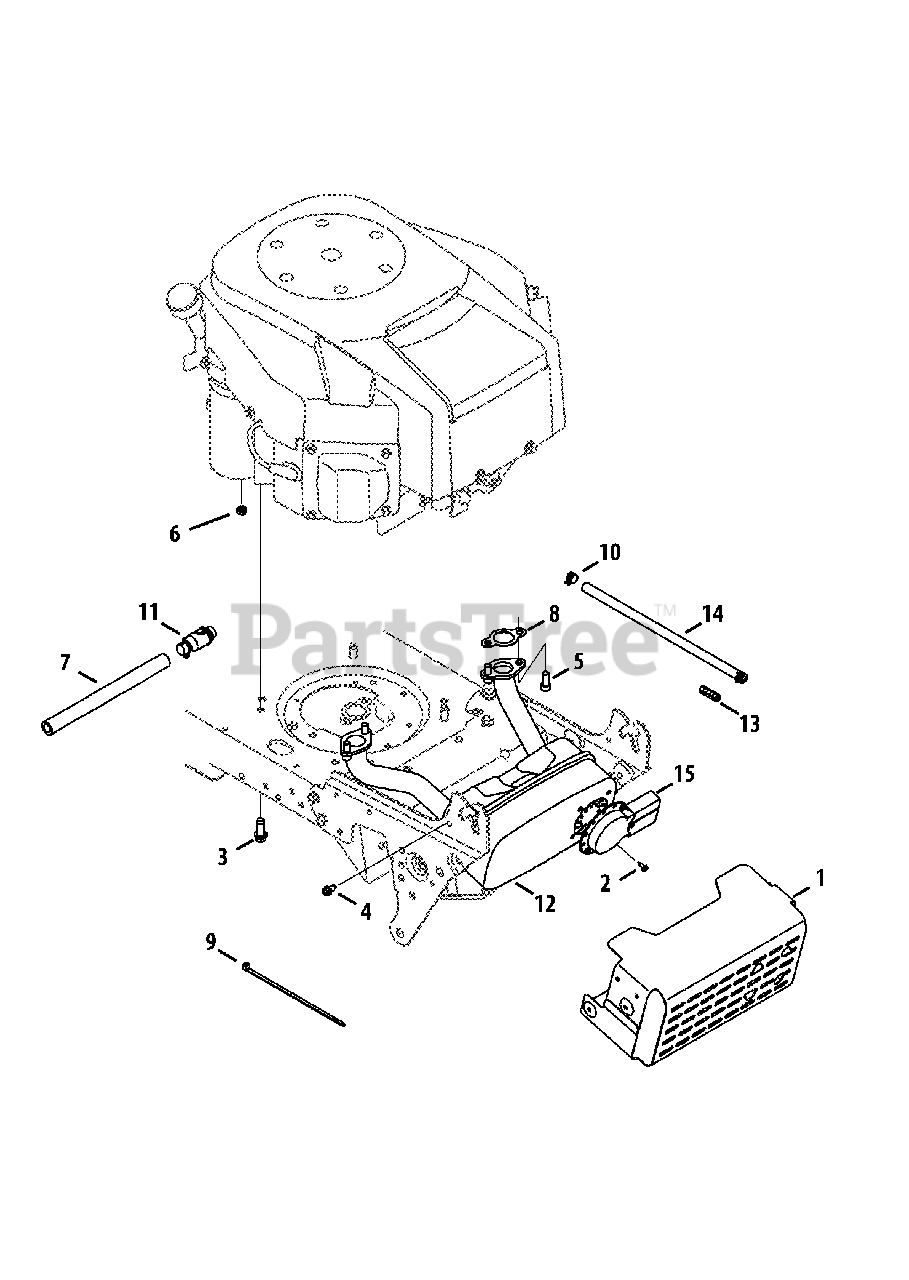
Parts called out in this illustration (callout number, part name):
1	Shield Ass’y, Muffler
2	Screw, Ab, #8-18, 0.500,
3	Screw, Self-tapping, 3/8-16, 1.000,
4	Screw, Self-tapping, 1/4-20, 0.500,
5	Screw, Socket Head, 5/16-18, .750
6	Nut, Sems, 1/4-20
7	Hose, Extension, Oil Drain
8	Gasket, Exhaust, Briggs
9	Cable, Tie, 3/16 x .05 x 7.4
10	Clamp, Hose, .490 Dia.
12	Muffler, Briggs Twin
14	Hose, Fuel, Low Permeation, 1/4
15	Deflector, Muffler, Long
